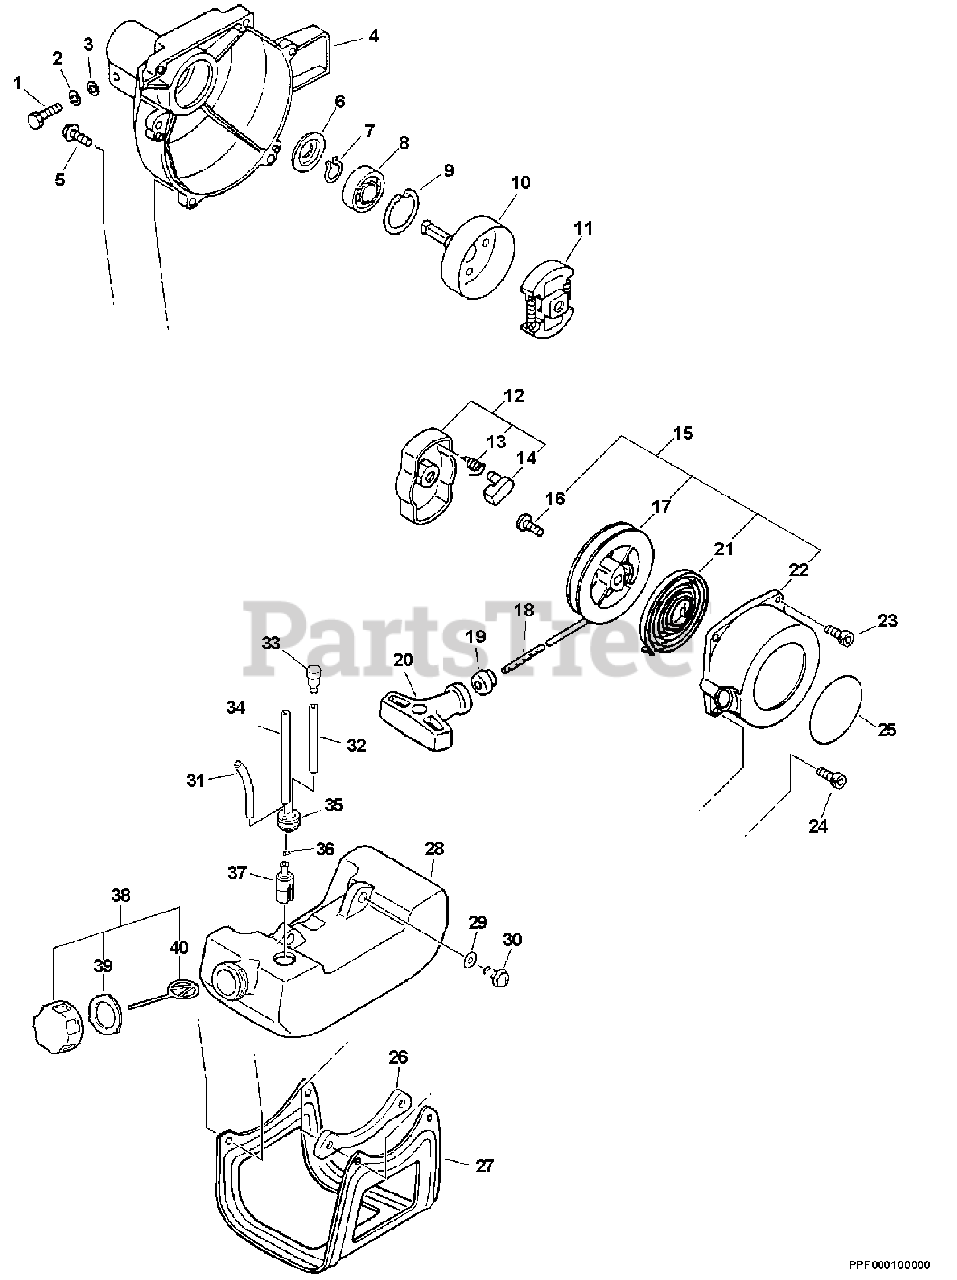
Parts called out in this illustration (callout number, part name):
1	BOLT 5×25
2	WASHER, SPRING 5
3	WASHER, FLAT 5.5×10×0.8
4	CASE, FAN
5	BOLT 4×16
6	STOPPER, PIPE
7	RING, RETAINING - 12
8	BEARING, BALL 6201-ZZ
9	RING, SNAP Ø32
10	DRUM, CLUTCH
11	CLUTCH ASSY
12	PAWL ASSY, STARTER
13	SPRING, RETURN
14	PAWL, STARTER - BLACK
15	STARTER ASSY, RECOIL
16	SCREW
17	REEL, ROPE
18	ROPE, STARTER 3.0×1000
19	GUIDE, ROPE
20	GRIP, STARTER
21	SPRING, RECOIL
22	CASE, RECOIL STARTER
23	BOLT 4×16
24	BOLT 4×20
25	LABEL - ECHO
26	PLATE, EYE
27	GUARD, FUEL TANK
28	TANK, FUEL
29	WASHER 5.5×12×0.8
30	SCREW 5×20
31	PIPE, FUEL RETURN 3×6×90 MM CLEAR
32	PIPE, FUEL 3x-5x-70 BLACK
33	VENT ASSY
34	PIPE, FUEL 3x-5x-180
35	GROMMET, FUEL
36	CLIP 6 MM
37	FILTER, FUEL
38	CAP ASSY, FUEL
39	GASKET, FUEL CAP
40	CONNECTOR, CAP L= 100 MM
